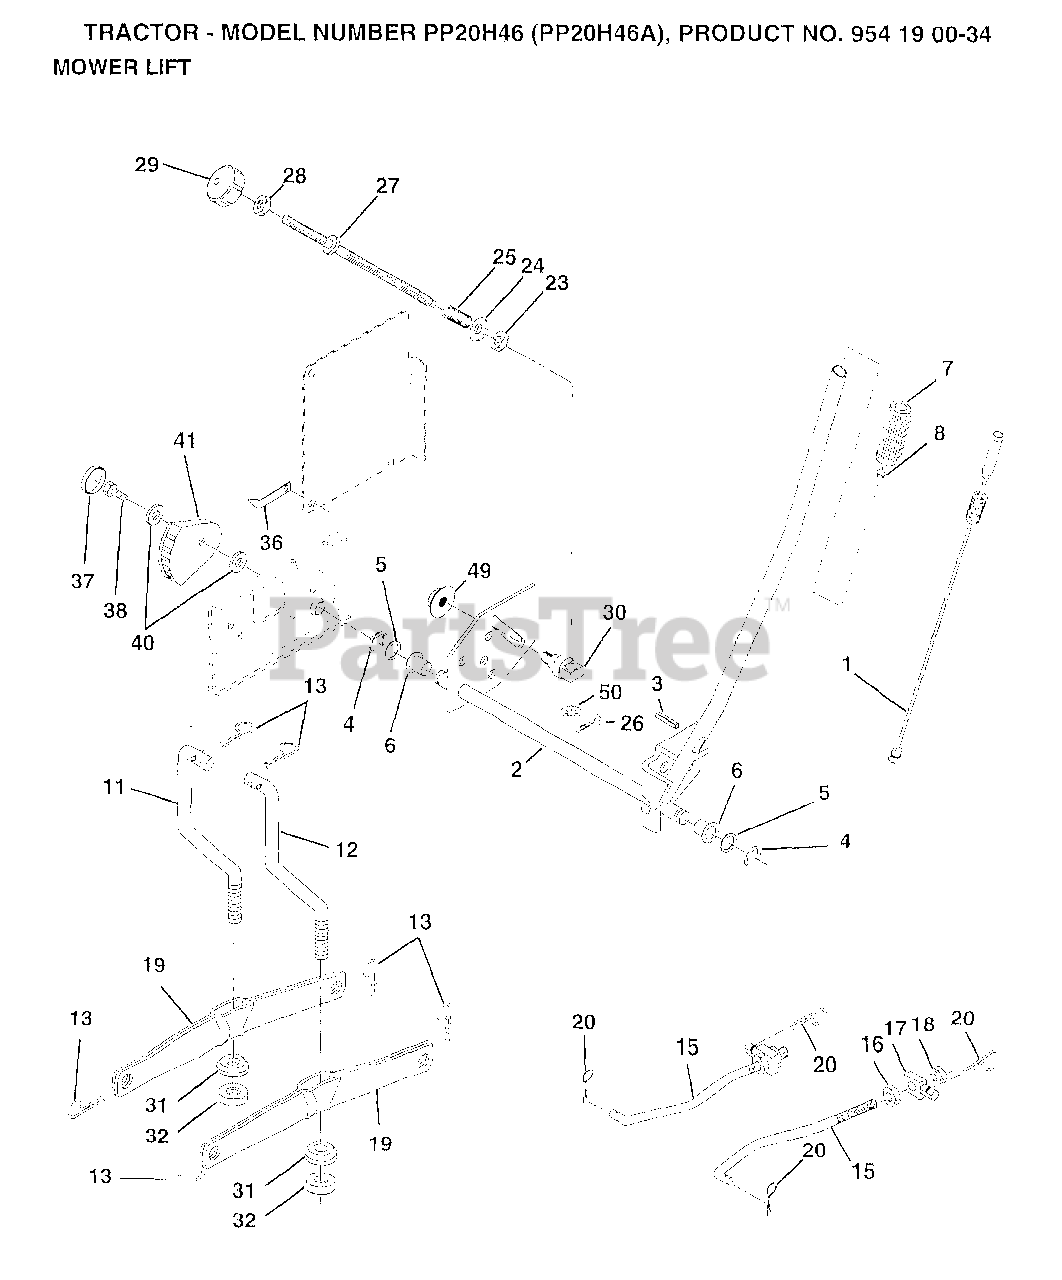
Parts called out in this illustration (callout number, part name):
1	WIRE ASM W.SPRING
2	"SHAFT ASM LIFT,RH"
3	PIN-GROOVE LT
5	WASHER
6	NYLON BEARING
7	GRIP
15	LINK.FRONT
16	NUT
17	TRUNION
18	NUT LTV
19	ARM SUSP REAR
20	RETAINER SPRING
23	NUT T
24	WASHER
25	SPRING T
28	NUT
29	KNOB INF 3/8-16
30	TRUNNION
31	BEARING PVT LH
32	NUT.CROWNLOCK.3/8
36	POINTER-INDICAT
37	"PLUG,HOLE"
38	SCREW
40	WASHER
41	INDICATOR HEIGHT
49	NUT.HXFLG.LOCK.
50	NUT PUSH M
